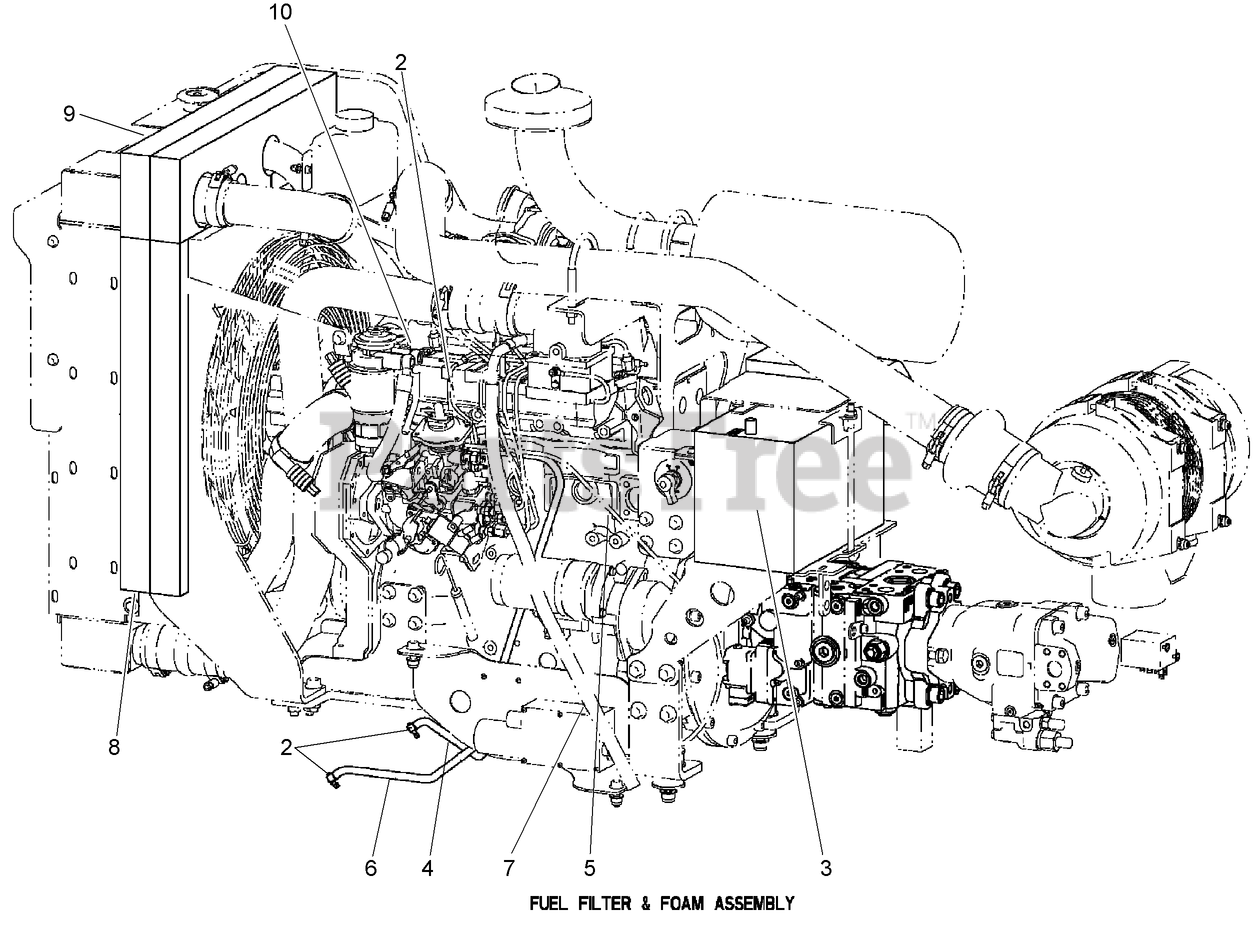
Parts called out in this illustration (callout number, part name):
2	CLAMP - Hose Type M # 06
4	FUEL LINE - 3/8 ID, 42 Length
5	FILTER-INLINE FUEL
6	FUEL LINE - Return, 3/8 ID, 40 Length
7	FUEL LINE - 3/8 ID, 16 Length
8	SEAL-FOAM
9	FOAM-SEAL
10	SPACER-FILTER, FUEL
